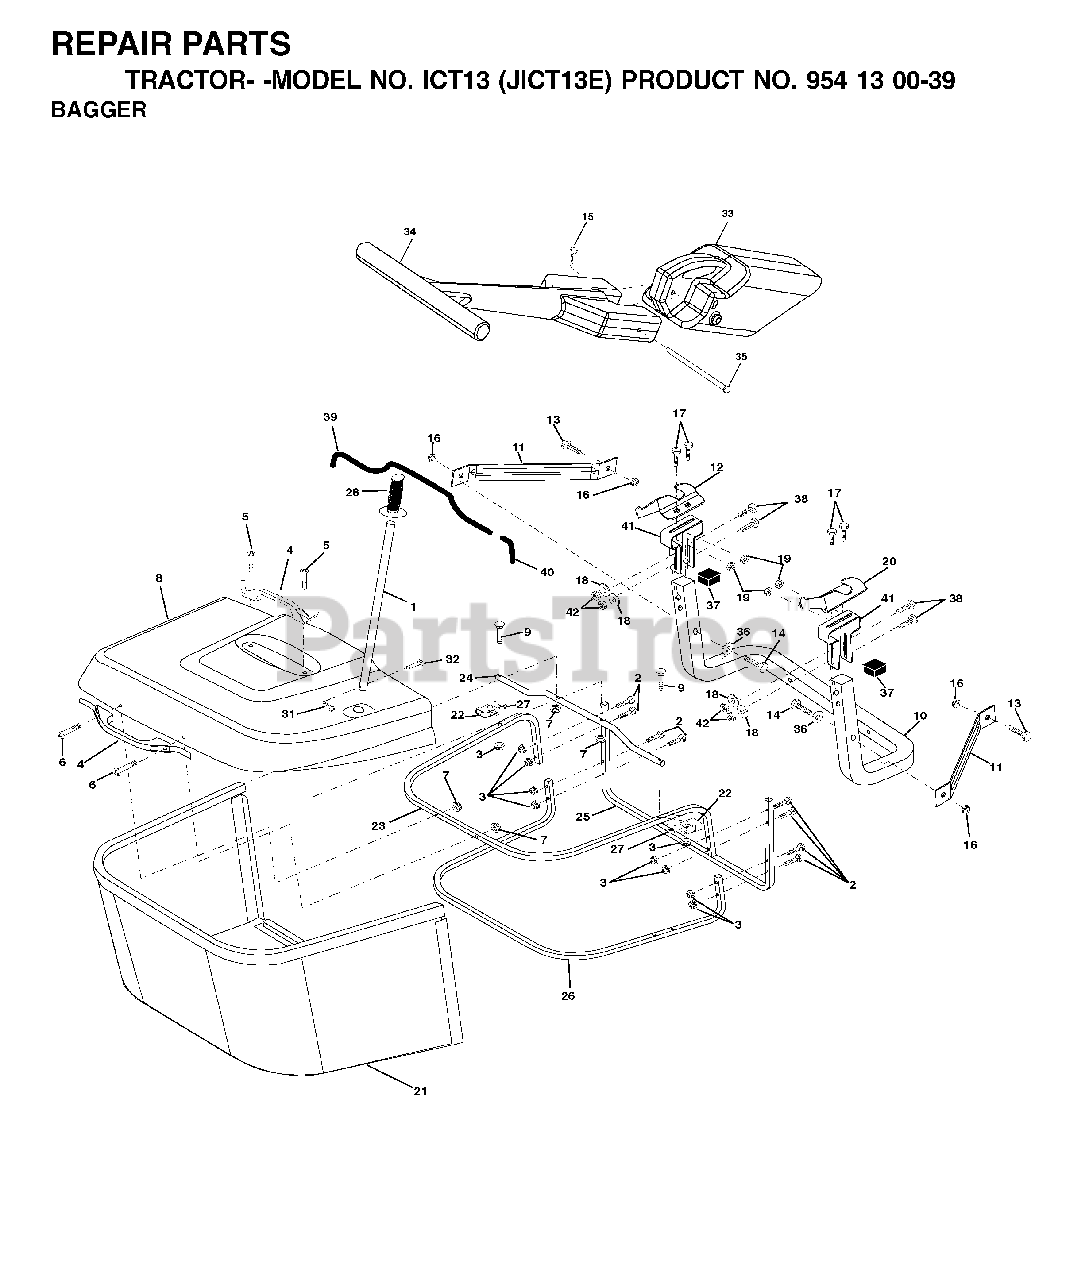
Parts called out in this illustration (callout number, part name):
1	TUBE HANDLE BAGGER
3	NUT T
5	SCREW.PAN.HEAD
10	TUBE
11	BRACKET
15	RETAINER-SPRNG RB
16	NUT LOCK FLG 3/8-16 UNC
17	BOLT
18	WASHER M
19	NUT LOCK HEX FLANGE 5/16-18
20	BRACKET
21	BAG
22	BRACKET
23	TUBE
24	TUBE
26	TUBE
31	RETAINER M
32	RIVET,DRILLED
33	PLUG
35	PIN
36	WASHER
38	BOLT.5/16-18X2.5
39	TRIM
40	TRIM
41	BRKT, BAGGER
42	NUT.71038.31-18.HEX.NYLOCK
